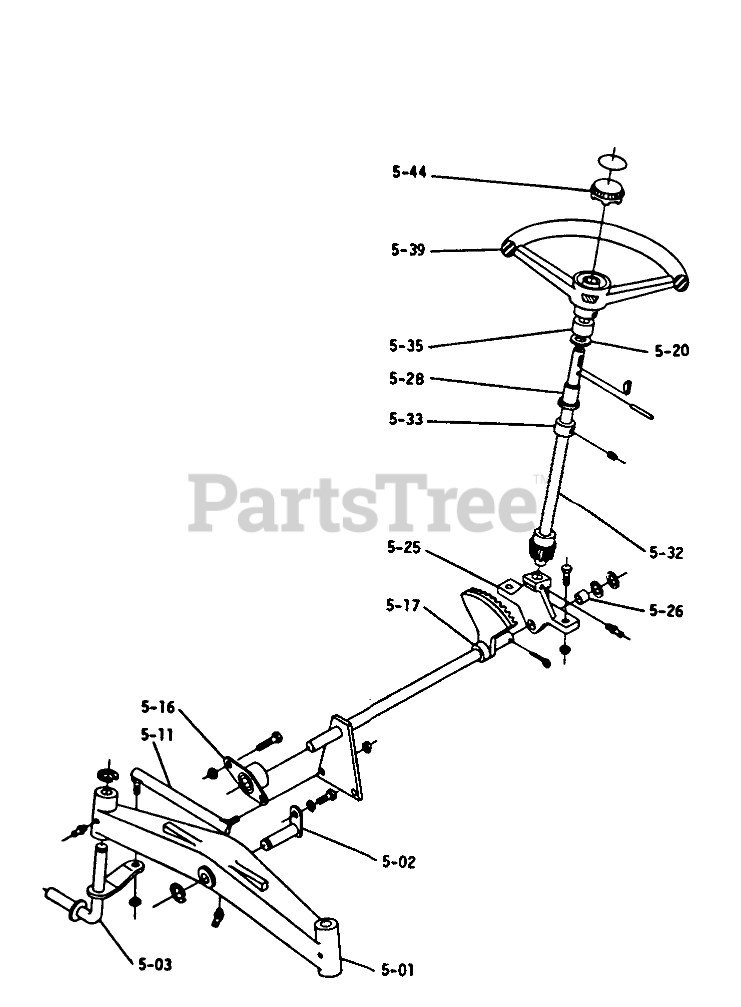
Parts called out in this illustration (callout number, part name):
5-01	AXLE-FRONT
5-01	Zerk
5-01	FITTING-GREASE
5-02	PIN AND PLATE ASM
5-02	Bolt Hex 5/16-18
5-02	Lockwasher
5-03	R.H. Spindle
5-03	Assy. Spindle-L.H.
5-03	E-RING
5-11	Tie Rod RH
5-11	Tie Rod LH
5-11	Locknut 3/8-24
5-16	BEARING-FLANGED
5-16	Bolt 3/8-16 x 1
5-17	Assy-Steering
5-17	WASHER-SHIM
5-17	603 1963 OPC
5-17	Cotter Pin
5-20	WASHER-BOWED
5-25	Support
5-25	Bolt 3/8-16 x 1
5-25	Zerk
5-26	BEARING-BRONZE
5-28	BEARING
5-32	ASSY UPPER STEER R
5-33	Collar
5-33	Set Screw Nylok
5-35	COLLAR
5-39	Steering
5-39	PIN-ROLL 1/4 X 1 1/4
5-39	Key
5-44	CAP INSERT
5-44	Decal
